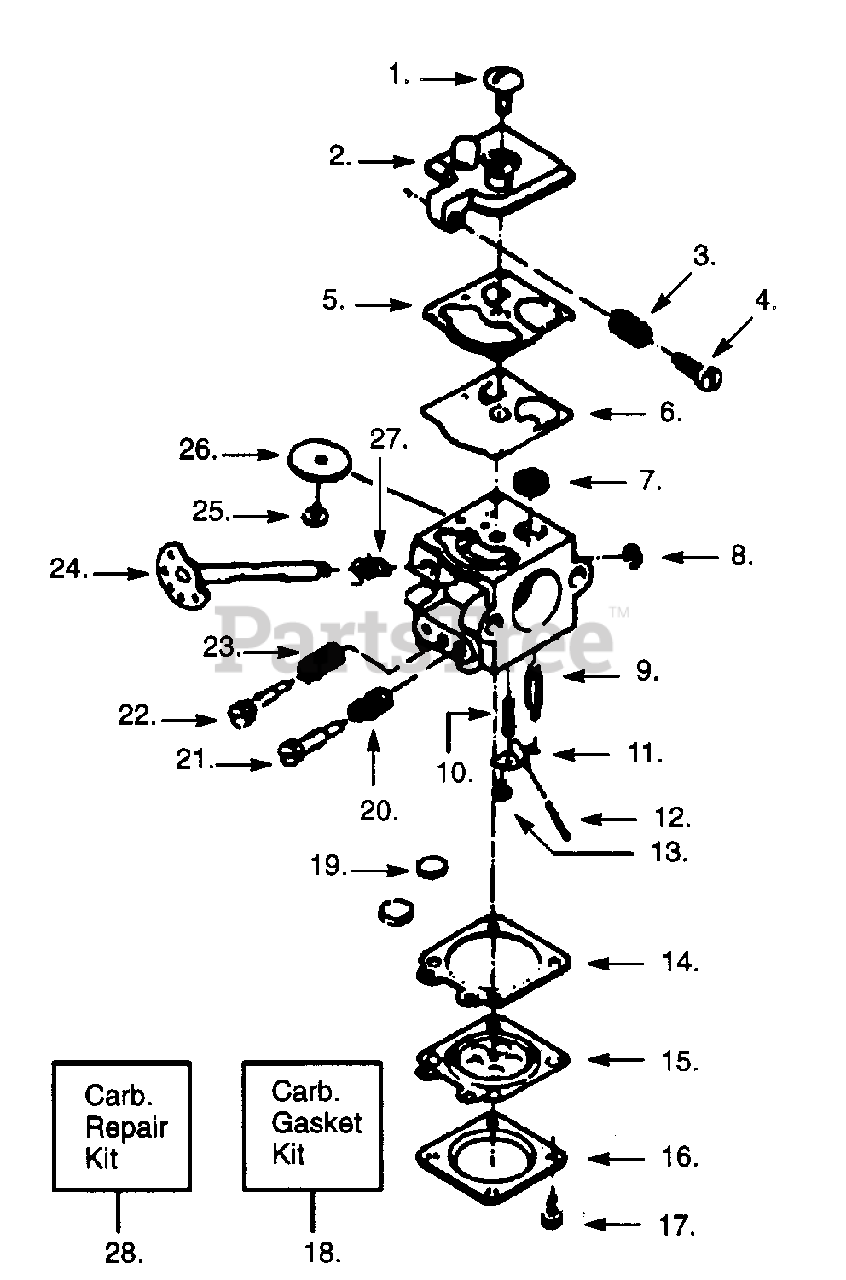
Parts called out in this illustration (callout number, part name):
1	Pump Cover Screw
2	Fuel Pump Cover
3	Spring-Idle Speed Adjusting Screw
4	Idle Speed Adjusting Screw
5	Fuel Pump Gasket
6	Fuel Pump Diaphragm
7	Fuel Inlet Screen
8	Throttle Retainer Ring
9	Inlet Needle Valve
10	Metering Lever Spring
11	Metering Lever
12	Metering Lever Pin
13	Screw-Metering Lever Pin
14	Metering Diaphragm Gasket
15	Metering Diaphragm
16	Metering Diaphragm Cover
17	Metering Cover Screw Ass'y.
18	Carb. Gasket/Diaphragm Kit
19	Plug-5/16 Dia. Welch
20	High Speed Mixture Needle Spring
21	High Speed Mixture Needle
22	Low Speed Mixture Needle
23	Low Speed Mixture Needle Spring
24	Throttle Shaft Ass'y.
25	Throttle Valve Screw
26	Throttle Valve
27	Throttle Return Spring
28	Carb. Repair Kit (Inc. 5-7,9-15,18,19)
29	Carb. Gasket/Diaphragm Kit (Inc. 5,6,14,15)
